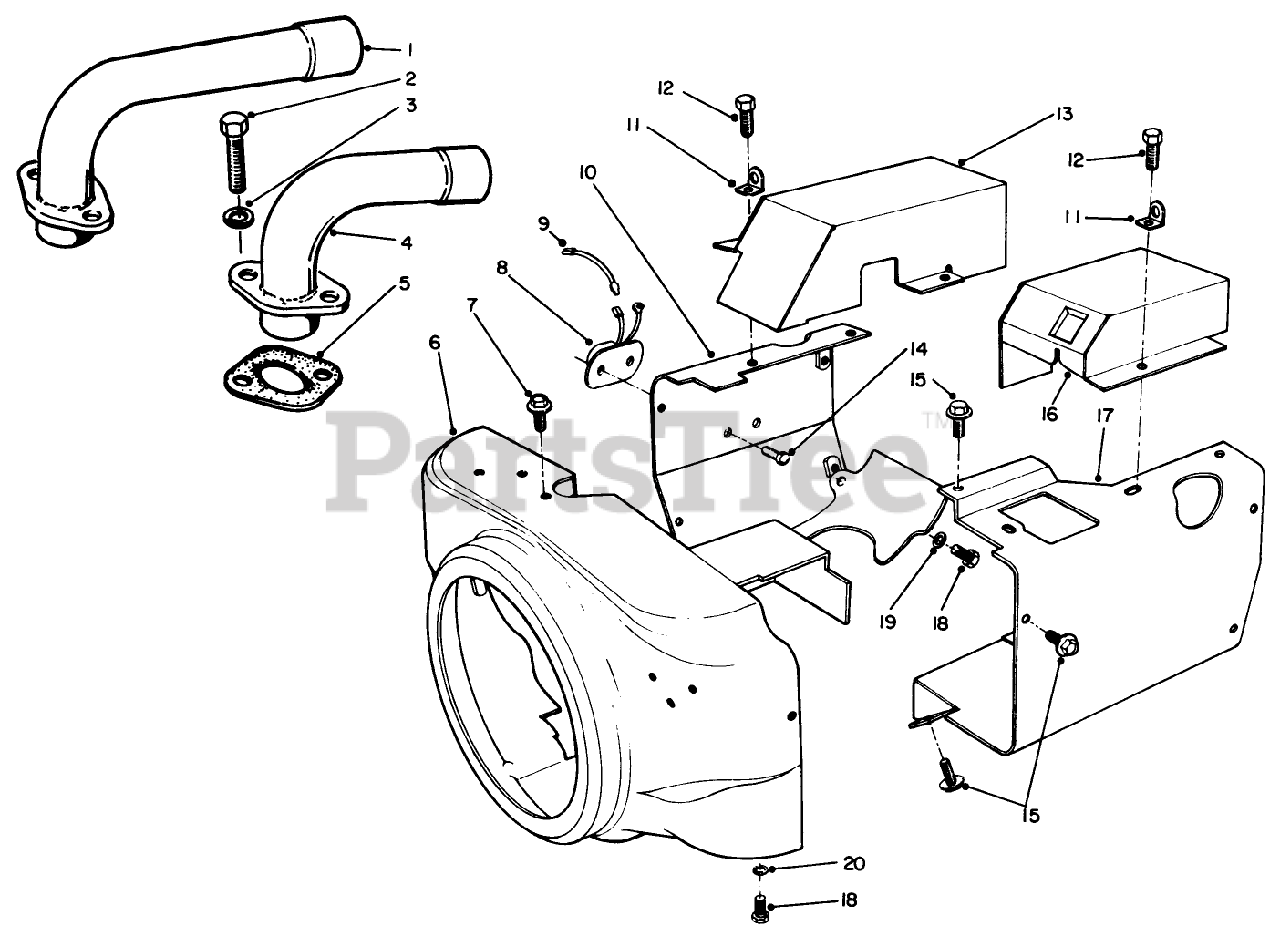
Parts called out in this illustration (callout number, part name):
1	Adapter, Exhaust-Left
2	Screw, Cap-Hex Hd.
3	Washer, Lock-Spring
4	Adapter, Exhaust-Right
5	Gasket, Exhaust
6	Housing, Blower
7	Screw, Cap-Hex. Hd.
8	Switch, High Air Temp. Cut Off
9	MANUAL-PARTS
10	Housing, Cylinder Air-Left Side
11	Bracket, Lifting
12	Screw, Tapping-Hex Hd.
13	Cover, Exhaust-Left
14	Rivet, High Air Temp. Cut Off
15	Screw, Cup Hex Washer Hd.
16	Cover, Exhaust-Right
17	Housing, Cylinder Air-Right Side
18	Screw, Cap-Hex Hd.
19	Washer, Flat
20	Washer, Flat
